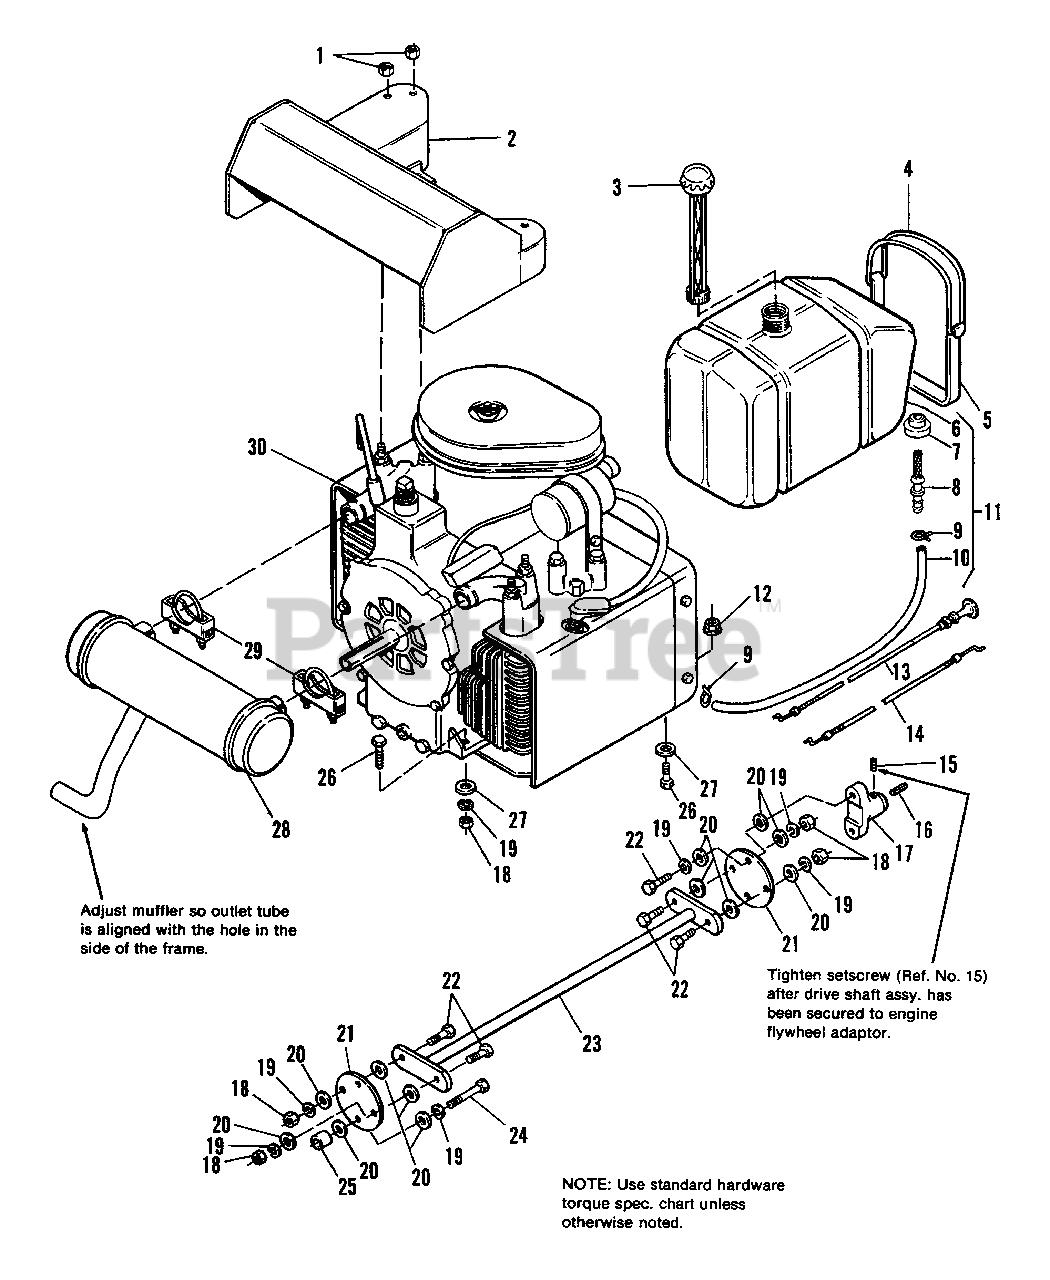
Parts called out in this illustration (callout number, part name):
1	LOCKNUT, Hex, Flange, 5/16-18
2	SHIELD ASSY., Heat
3	CAP, Fuel Tank
4	STRAP, Fuel Tank
5	STRAP, Tank
9	CLAMP, Hose
11	TANK ASSY., Fuel
12	LOCKNUT, Hex, Flange, Whiz, 3/8-16
13	CONTROL, Choke
14	CONTROL, Throttle
15	SETSCREW, 3/8-24 x 3/8
17	FLANGE, Drive Shaft
18	NUT, Hex, Full, 3/8-16
19	LOCKWASHER, 3/8
20	WASHER, Special
22	CAPSCREW, Hex Hd., 3/8-16 x 1-1/4
23	SHAFT ASSY., Drive
24	CAPSCREW, Hex Hd., 3/8-16 x 2-1/4
26	CAPSCREW, Hex Hd., 3/8-16 x 1-1/2
27	WASHER, Plain, 3/8
28	MUFFLER, Exhaust
29	CLAMP, Exhaust
30	ENGINE, 17 HP Kohler
30	ENGINE, 19 HP Kohler Twin
